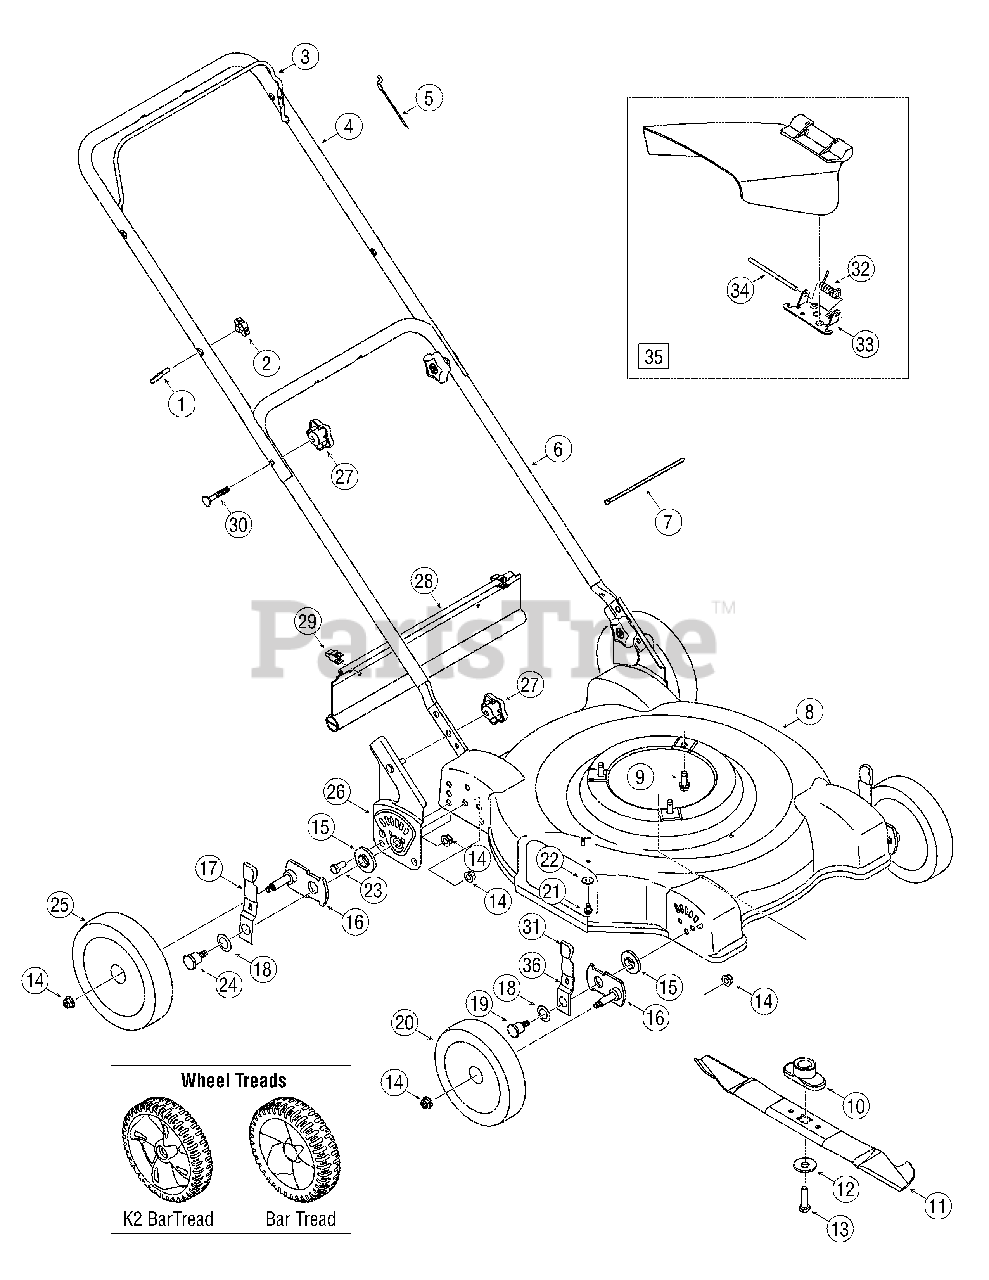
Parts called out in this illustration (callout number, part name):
1	Eye Bolt
2	Wing Nut
5	Blade Control Cable - 37.25 inch
5	Blade Control Cable - 48.25 inch
5	Blade Control Cable - 40.00 inch
7	Cable Tie
9	TT Screw 3/8-16 x 1.0
10	Blade Adapter
11	Standard Blade 22-inch
12	Washer, Bell, .396 x 1.140 x .095
13	Screw 3/8-24 x 1.5
14	Lock Nut 3/8-16
15	Height Adjuster Bearing
16	Pivot Arm
17	Lever Assembly (Includes Ref. # 31 & 36)
18	Bell Washer .760 ID x 1.25 OD
19	Shoulder Screw
20	Front Wheel, 7 x 1.8, K2 Bar
20	Front Wheel, 7 x 1.8, Bar
21	TT Screw 1/4-20 x .5
22	Bell Washer .265 ID x .75 OD
23	Screw 3/8-16 x .75
24	Shoulder Screw
25	Rear Wheel, 8 x 1.8, K2 Bar
25	Rear Wheel, 8 x 1.8, Bar
27	Star Knob
28	Trailshield
29	Hinge Clip
30	Carriage Bolt 5/16-18 x 2
31	Knob
32	Torsion Spring
33	Chute Hinge
34	Hinge Pin
35	Hinged Chute Deflector Assembly
36	Spring Lever
